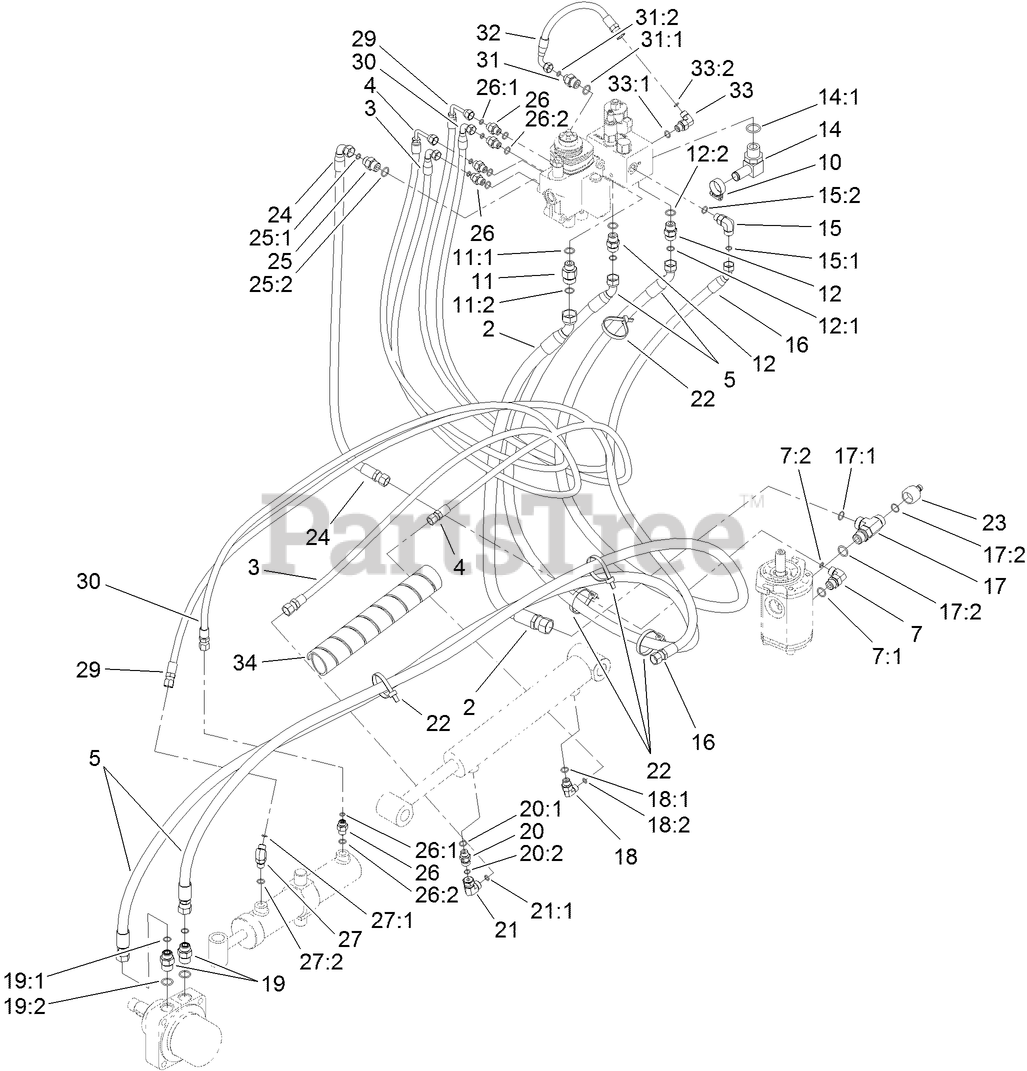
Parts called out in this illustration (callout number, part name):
2	HOSE-HYD
3	HOSE-HYD
4	HOSE-HYD
5	HOSE-HYD
7	FITTING-HYD, 90 DEG
7:1	O-RING
7:2	O-RING
10	CLAMP-HOSE
11	FITTING-STR
11:1	O-RING
11:2	O-RING
12	FITTING-STRAIGHT
12:1	O-RING
12:2	O-RING
14	FITTING-ELB 90
14:1	O-RING
15	FITTING-ELBOW, 90 DEG
15:1	O-RING
15:2	O-RING
16	HOSE-HYD
17	FITTING-TEE
17:1	O-RING
17:2	O-RING
18	FITTING-ELBOW 90
18:1	O-RING
18:2	O-RING
19	FITTING-STRAIGHT
19:1	O-RING
19:2	O-RING
20	VALVE-CHECK
20:1	O-RING
20:2	O-RING
21	FITTING-HYD, 90 DEG
21:1	O-RING
22	TIE-CABLE
23	NIPPLE
24	HOSE-HYD
25	FITTING-STRAIGHT
25:1	O-RING
25:2	O-RING
26	FITTING-STRAIGHT
26:1	O-RING
26:2	O-RING
27	FITTING
27:1	O-RING
27:2	O-RING
29	HYD HOSE ASM
30	HYD HOSE ASM
31	FITTING-STR
31:1	O-RING
31:2	O-RING
32	HOSE-HYD
33	FITTING-ELBOW 90
33:1	O-RING
33:2	O-RING
34	WRAP-SPIRAL
